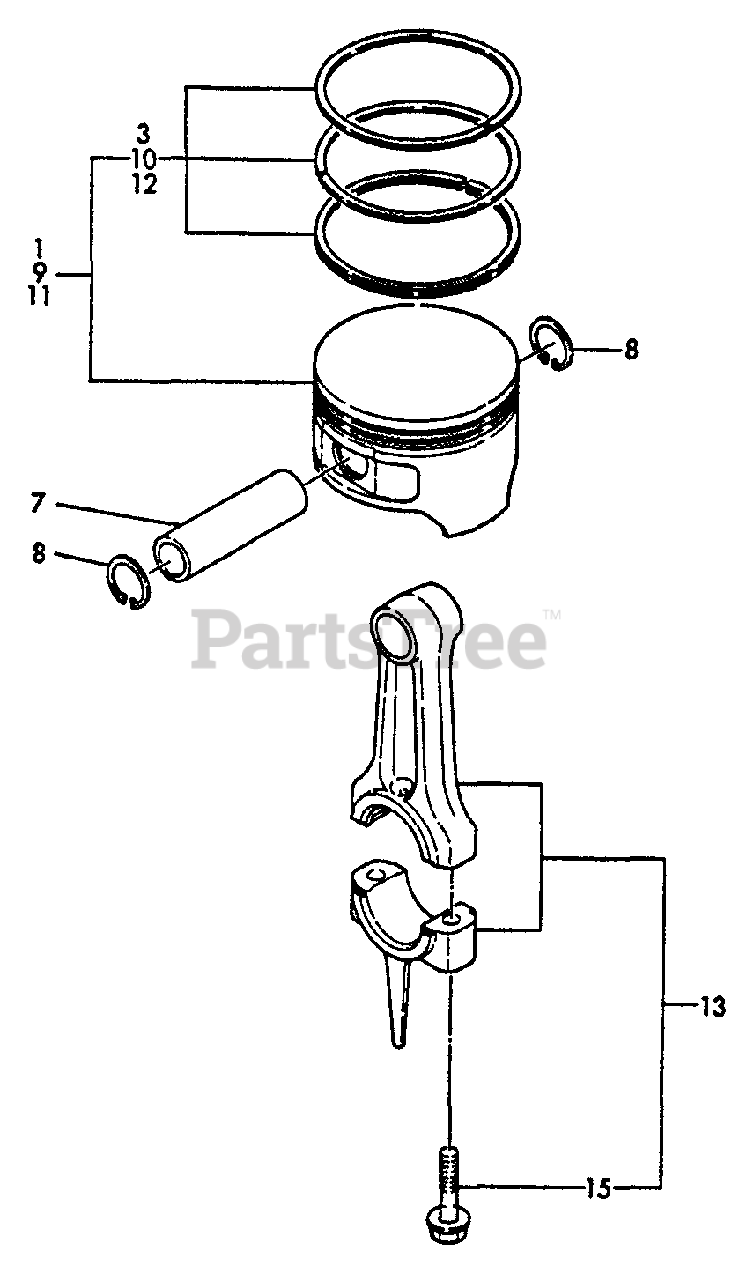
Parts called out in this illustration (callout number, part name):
1	PISTON ASSY
3	PISTON RING ASSY
7	PIN, PISTON
8	RING, RETAINING - 19
9	PISTON ASSY O.S.= 0.25
10	RING ASSY O.S.= 0.25
11	PISTON ASSY O.S.= 0.5
12	RING ASSY O.S.= 0.5
13	CONNECTING ROD ASSY
15	BOLT, ROD
